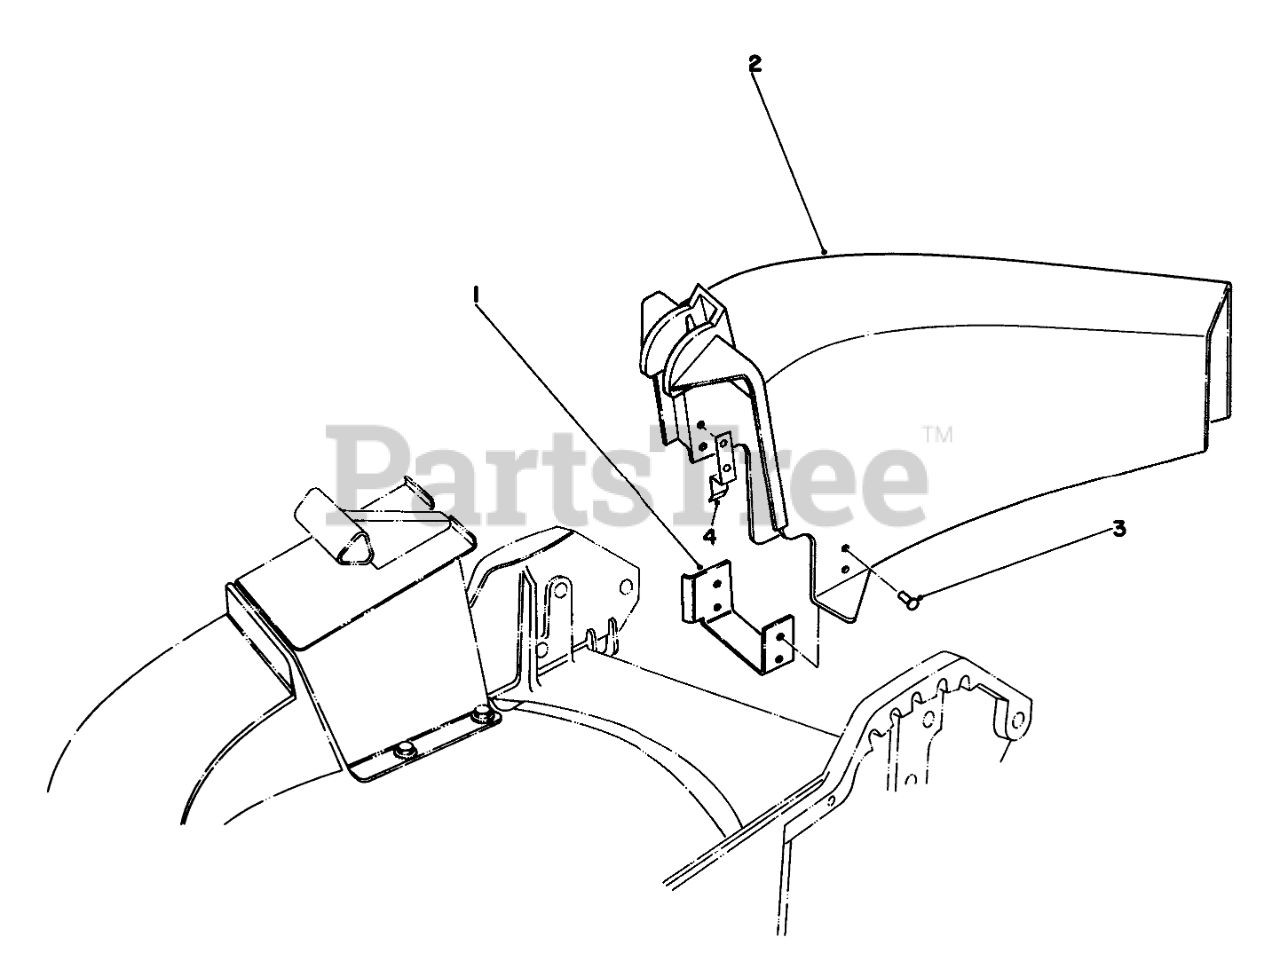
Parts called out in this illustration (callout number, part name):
1	CHUTE BRACKET
2	Chute Discharae
3	RIVET
4	CHUTE TAB
